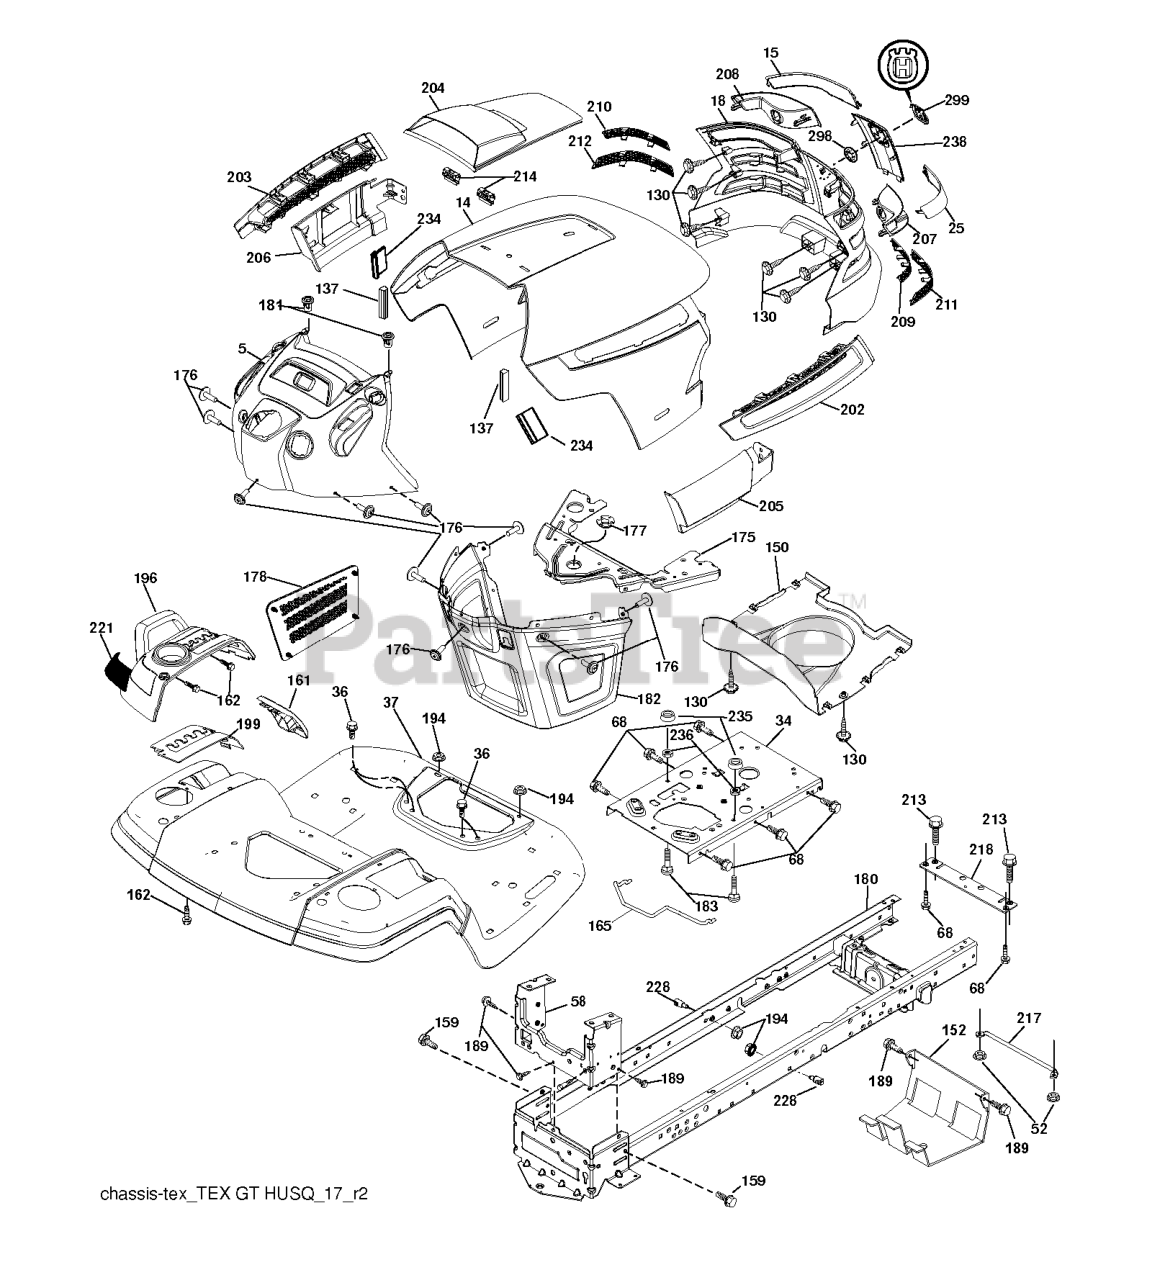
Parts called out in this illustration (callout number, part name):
5	DASH.ASM.HUSQ.GT.E.RECT.W/CK
14	HOOD
15	LENS.LH.TEX.GT.HUSQ.CL
18	GRILL.ASM.HUSQ.TG/CRD.W/TRIM
25	LENS.RH.TEX.GT.HUSQ.CL
34	PLATE.ENGINE.WELDED.CHASSIS
36	SCREW 5/16"
37	FENDER.PNT.TX.GT.CH/FW.ORANGE
52	LOCKNUT
58	DRAWBAR.UPPER.2PC,LRG.FENDER
68	Screw 5/16-18 x 1/2 Hex, Self Tapping 5/16-18 x 1/2
130	SCREW.#10 X 0.750.BOS
137	BUMPER DASH
150	AIR.DUCT.HOOD.TEX.GT.HUSQ
152	SHIELD.BROWNING.W/TEX
159	SCREW, 3/8-16X3/4
161	CONSOLE.FUEL.WINDOW.HU
162	SCREW.HI-LO.CONSOLE
165	SUPPORT.TANK.REAR.W/TEX
175	PLATE.CROSSMEMBER.HUSQ
176	SCREW.#10-24X5/8.RN.QU
177	BUSHING, STEERING
178	CARGO.ASM.NET.TXGT.W/C
180	CHASS.WLDMNT.TLT.12GA/2PC.20"
181	BUSHING.MNT.FEND.CRGO.
182	DASH.LOWER.COMMON.12V.ADAPTOR
183	BOLT.5/16-18X1-1/4 FULL THD
189	SCREW
194	NUT LOCK HEX FLANGE 5/16-18
196	RP CONSOLE.ASM.DECKLFT.W/
199	PLATE.DECK.LIFT.HUSQVARNA.GT
202	VENT.SIDE.HOOD.HUSQ.RH.GREY
203	VENT.SIDE.HOOD.HUSQ.LH.GRAY
204	HOOD VENT
205	SKIRT.HOOD.SIDE.HUSQ.RH.GREY
206	SKIRT.HOOD.SIDE.HUSQ.LH.GREY
207	BEZEL.RH.TEX.GT.HUSQ
208	BEZEL.LH.TEX.GT.HUSQ
209	INSERT.HEX.GRILL.HUSQ.GREY
210	INSERT.HEX.GRILL.HUSQ.
211	INSERT.HEX.GRILL.HUSQ.
212	INSERT.HEX.GRILL.HUSQ.
213	BOLT
214	CLIP.RETAINER.TINNER.
217	ROD.PIVOT.HOOD
218	X-PIECE.HOOD.STOP.NON/
221	REFLECTOR.LH.TEX GT HU
228	STUD.FASTNER.W/ANTI-ROTATE
234	BUMPER.HOOD.TEX.HUSQVARNA
235	SPACER FENDER
236	NUT.CENTERLOCK.5/16-
238	TRIM.HUSQ.TG/CRD.SERVICE
298	NUT PUSH M
299	RP LOGO
